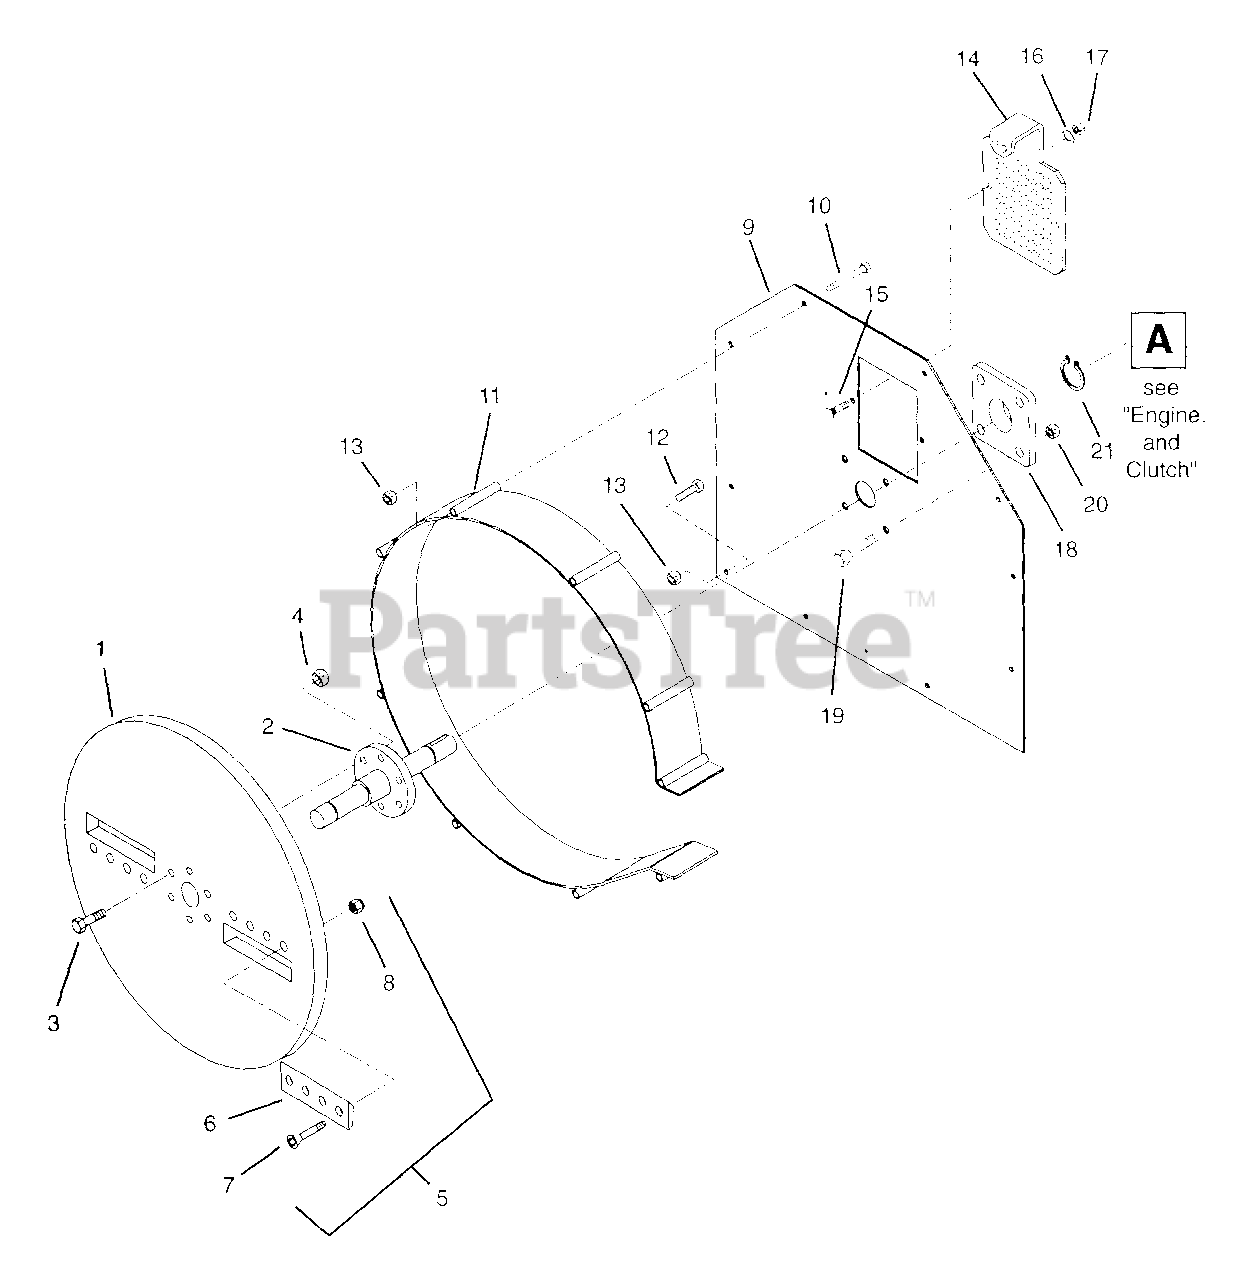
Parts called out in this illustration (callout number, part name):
1	Flywheel
2	Shaft-Flywheel
3	Bolt-Hex .50-13 x 2.00 Grade 5
4	Nut-Locking-Center .50-13
5	Chipper Knife Set - 210/PTO
7	Bolt-Flat Socket Head .50-13 x 1.75 Grade 8
8	Nut-Locking-Crown .50-13 Grade C
9	Blower Side, Left Hand
10	Bolt-Hex .38-16 x 5.75 Grade 5
11	Drum Strap Weldment
12	Bolt-Hex .38-16 x .75 Grade 5
13	Nut-Locking-Center .38-16
14	Plate, Knife Access
15	Bolt-Carriage Special Ribbed .38-16 x 1.0 Grade 5
16	Washer-Lock .38 x .094
17	Nut-Hex .38-16
18	Bearing-Flange 1.500 x 4 Bolt x 2.047
19	Bolt-Lug,50-20 x 1.50
20	Nut-Locking-Center .50-20
21	Retaining Ring-External 1.500 x .109
